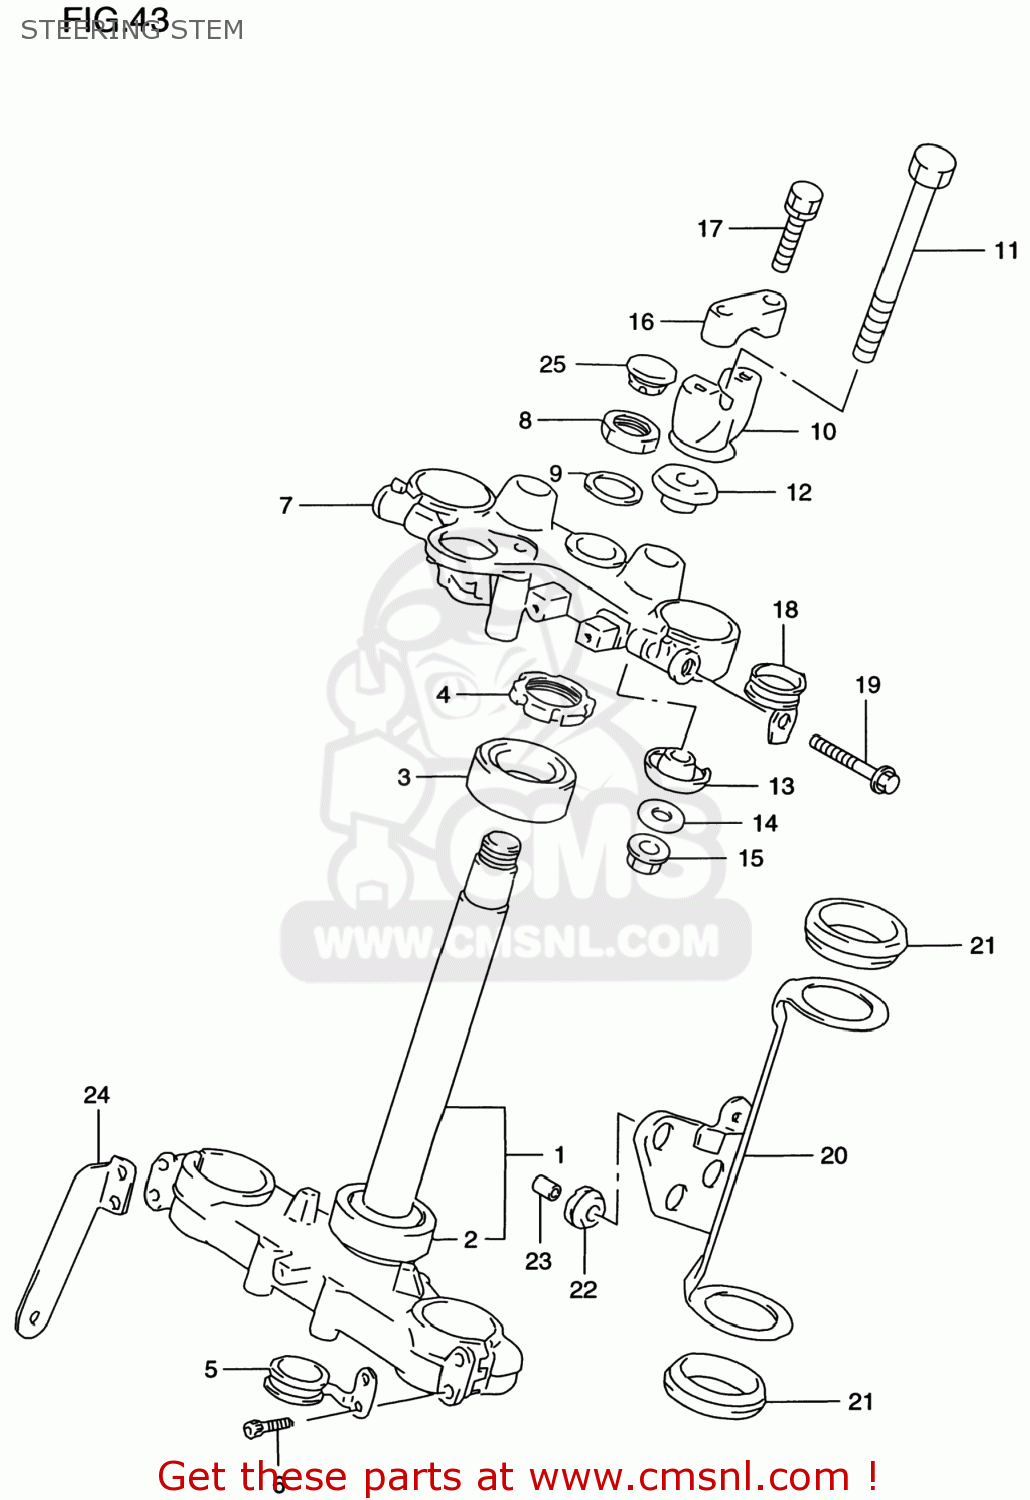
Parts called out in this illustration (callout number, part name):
1	STEM,STEERING
2	BEARING(30X52X16)
3	BEARING(30X52X16)
4	NUT,STEERING
5	CLAMP
6	BOLT
7	HEAD,STEERING STEM
8	NUT
9	WASHER,STEM HEAD(24.5X34X1.6)
10	HOLDER,HANDLE LWR
11	BOLT
12	DAMPER,UPR
13	DAMPER,LWR
14	WASHER(10.5X28X2.3)
15	NUT
16	HOLDER,HANDLE UPR
17	BOLT
18	CLIP
19	BOLT
20	COVER,FORK,R
21	DAMPER,HEADLAMP HSG BRACKET
22	CUSHION
23	SPACER(6.5X10X10)
24	BRACKET,FR SIDE REFLECTOR,R
25	CAP(OD:20)
